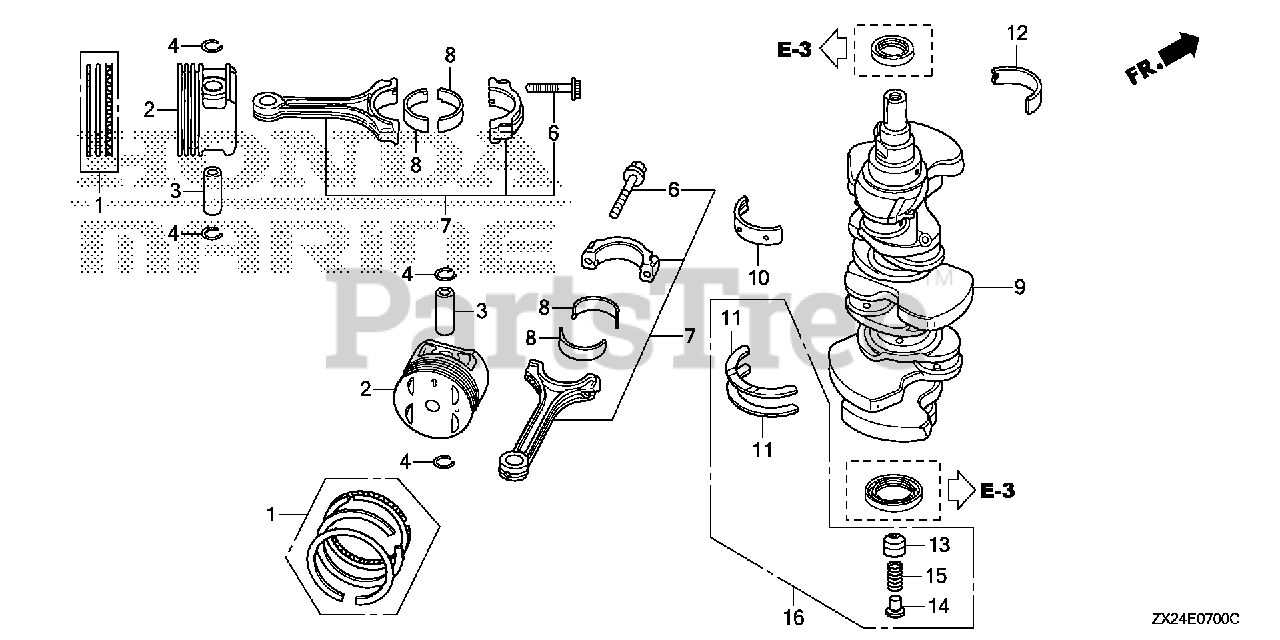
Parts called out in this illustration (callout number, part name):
1	RING SET, PISTON (STD) (RIKEN)
1	RING SET, PISTON (0.25) (RIKEN)
2	PISTON (0.25)
3	PIN, PISTON
4	CLIP, PISTON PIN
6	BOLT, CONNECTING ROD
7	ROD, CONNECTING
8	BEARING A, CONNECTING ROD (BLACK) (TAIHO)
8	BEARING B, CONNECTING ROD (BROWN) (TAIHO)
8	BEARING C, CONNECTING ROD (GREEN) (TAIHO)
8	BEARING D, CONNECTING ROD (YELLOW) (TAIHO)
8	BEARING E, CONNECTING ROD (PINK) (TAIHO)
9	CRANKSHAFT
10	BEARING A, MAIN (UPPER) (BLACK) (TAIHO)
10	BEARING B, MAIN (UPPER) (BROWN) (TAIHO)
10	BEARING C, MAIN (UPPER) (GREEN) (TAIHO)
10	BEARING D, MAIN (UPPER) (YELLOW) (TAIHO)
10	BEARING E, MAIN (UPPER) (PINK) (TAIHO)
10	BEARING F, MAIN (UPPER) (RED) (TAIHO)
11	WASHER, THRUST
12	BEARING A, MAIN (LOWER) (BLACK) (TAIHO)
12	BEARING B, MAIN (LOWER) (BROWN) (TAIHO)
12	BEARING C, MAIN (LOWER) (GREEN) (TAIHO)
12	BEARING D, MAIN (LOWER) (YELLOW) (TAIHO)
12	BEARING E, MAIN (LOWER) (PINK) (TAIHO)
12	BEARING F, MAIN (LOWER) (RED) (TAIHO)
13	RETAINER, SPRING
14	SEAT, SPRING (250)
15	SPRING, SUPPORT
